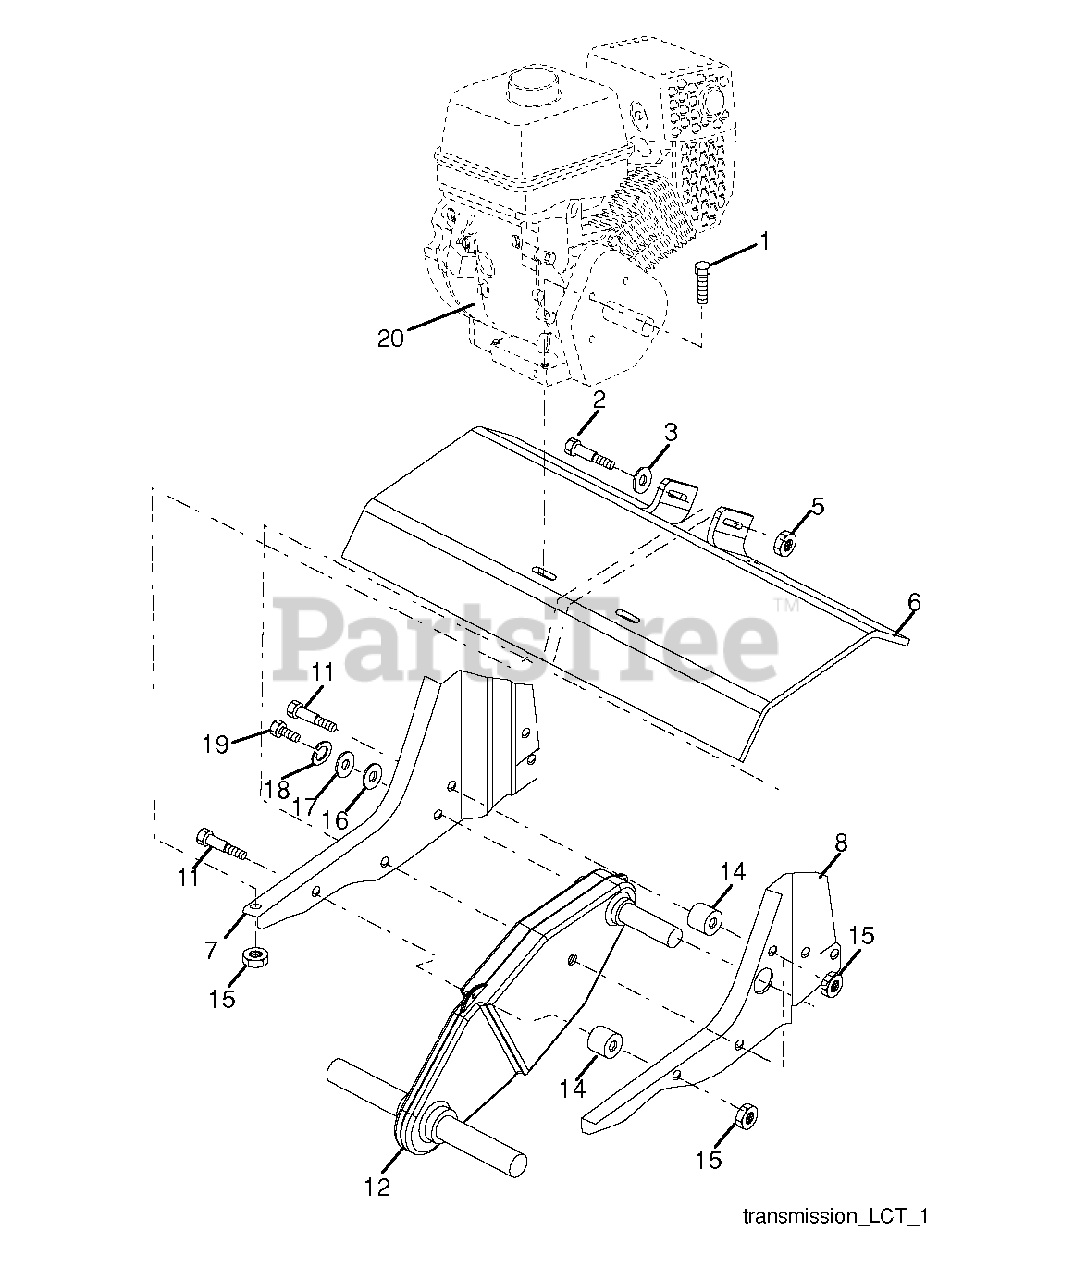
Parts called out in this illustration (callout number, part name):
1	BOLT
5	NUT LOCK FLG 3/8-16 UNC
7	RP BRACKET, ENGINE, R.H.
8	BRACKET.ENGINE.TILLER.LH.BLACK
11	BOLT, HEX HEAD 5/16-18 X 2.5
12	TRANSMISSION.ASM.W/1".D-SHAFT
15	LOCKNUT-FLANGE 5/16-18
18	LOCKWASHER
20	ENGINE.LCT.8.00.FT.LBS.MAN
